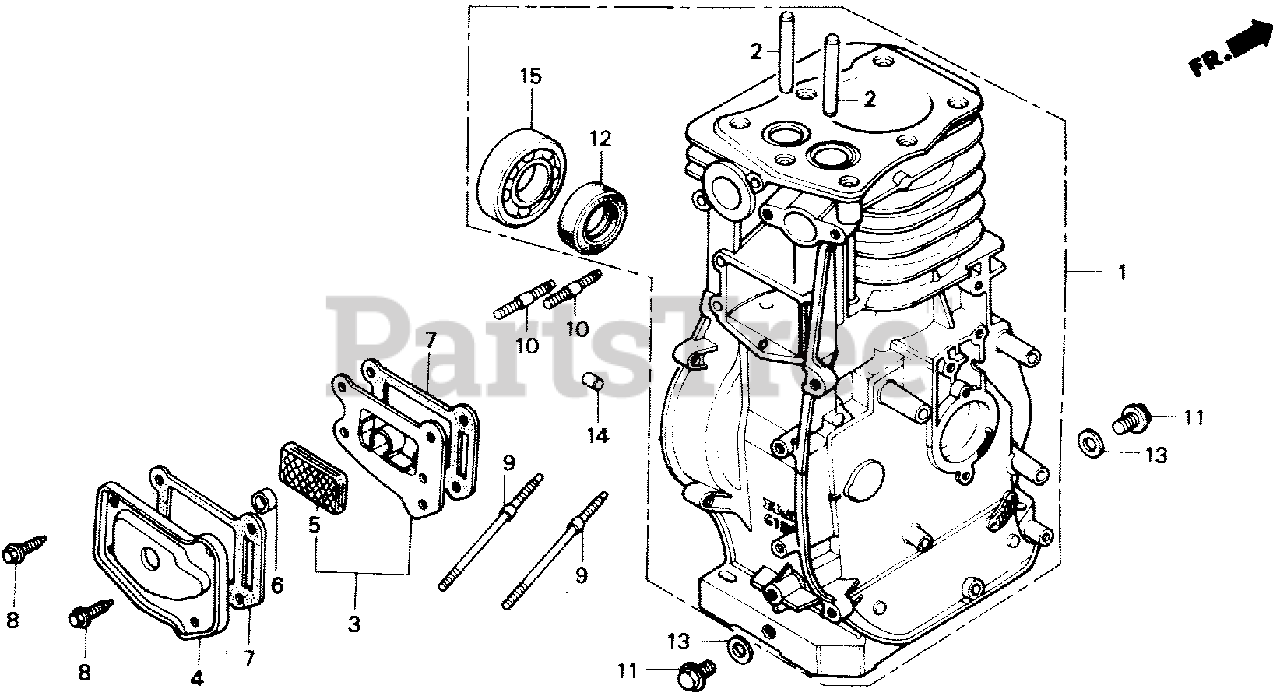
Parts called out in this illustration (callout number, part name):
1	CYLINDER ASSY.
2	GUIDE, VALVE (OVER SIZE)
3	CASE, BREATHER
4	COVER, TAPPET ROOM
5	FILTER, BREATHER
6	SEAL, BREATHER
7	GASKET, TAPPET COVER
8	BOLT, FLANGE (6X12) (CT200)
9	BOLT, STUD (6X89)
10	BOLT, STUD (8X35)
11	BOLT, DRAIN PLUG (12X15)
12	OIL SEAL (25X41X6)
13	WASHER, DRAIN PLUG (12MM)
14	PIN, DOWEL (8X14)
15	BEARING, RADIAL BALL (6205)
